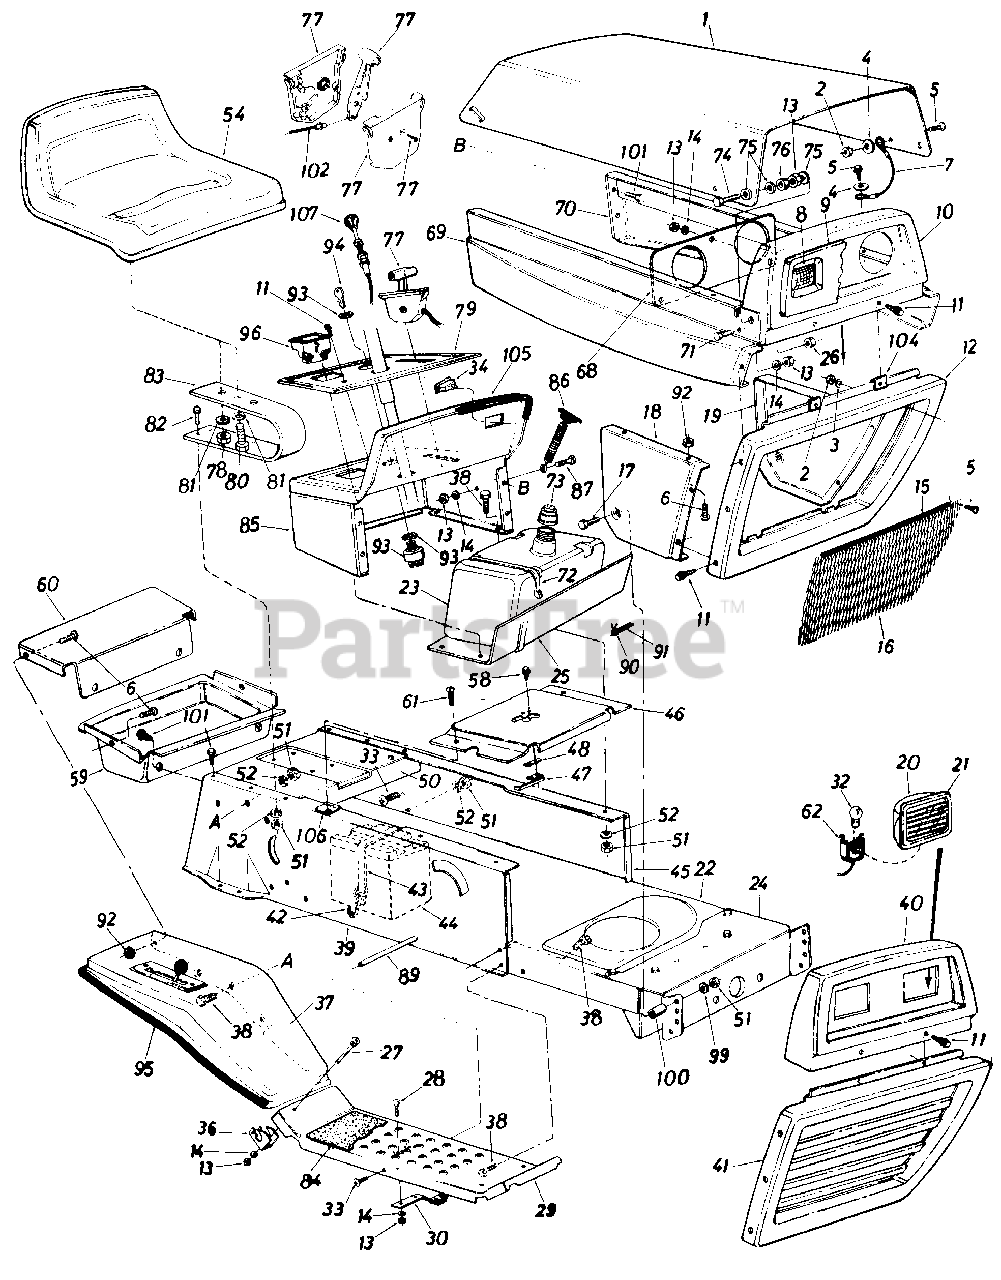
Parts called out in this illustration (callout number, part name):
3	L-Wash. #10 I.D.
4	Fl-Wash. .25" I.D. x .62"
5	Truss Scr. #10-24 x .375"*
6	Truss Hd. Scr. #10-24 x .50"*
7	Hood Stop
8	Headlight
9	Headlight Bezel
10	Front Grille Upper Ass'y.
11	Hex AB-Tap Scr. #10 x .50"
12	Lower Grille
13	Hex Nut 1/4-20 Thd.
14	L-Wash 1/4" I.D.*
15	Vinyl "U"-Channel
16	Grille Screen
17	Hex Bolt 5/16-18 x 1.50"*
18	R.H. Lower Side Panel
19	L.H. Lower Side Panel
20	Headlight Housing
21	Headlight Lens
22	Lower Frame
23	Fuel Tank
24	Front Pivot Brkt.
25	Fuel Tank Support
26	Hex Cent. L-Nut 3/8-16 Thd.
27	Carriage Bolt 1/4-20 x 2.00"*
28	Carriage Bolt 1/4-20 x .62"*
29	Running Board
30	Blade Brake Ass'y.
32	Head Lamp
33	Truss Mach. Scr. 5/16-18 x .75" Lg.*
34	Light Switch
36	Fender Clamp
37	Fender
39	R.H. Side Frame
40	Front Upper Grille Assy.
43	Battery Hold Down Strap
44	12-V Battery
45	L.H. Side Frame
46	Shift Cover
47	Reverse Safety Switch
48	Insulator Nut Plate
50	Hitch Plate
51	Hex Nut 5/16-18 Thd.*
52	L-Wash. 5/16" I.D.*
54	Seat Ass'y.
58	Hex AB-Tap Scr. #8 x .50"
59	Tool Tray
62	Twist Lock-Lamp Socket
68	Head Lamp Retainer
69	Side Panel-R.H.
70	Side Panel-L.H.
71	Hex Bolt 1/4-20 x .62" Lg.*
72	Tie Strap
73	Fuel Cap Gauge
74	Hex Bolt 3/8-16 x 1.00" Lg.*
75	Fl-Wash. 380" I.D. x 1.00"
76	Rubber Wash. .38" I.D. x .87" O.D.
77	Throttle Control Box Ass'y.
78	Hex Nut 1/2-13 Thd.
79	Dash Panel Insert
80	Hex Bolt 1/2-13 x 1.00" Lg.
81	L-Wash. 1/2" I.D.*
82	Hex Bolt 5/16-18 x 1.00"*
83	Seat Spring
84	Foot Pad
87	Hex Bolt 1/4-20 x .50" Lg.*
89	Running Board Rod
90	Hose Clamp
91	Fuel Line
92	Hex Sems Nut #10-24 Thd.
93	Ignition Switch
94	Ignition Key
95	Trim Strip-57" Lg.
96	Ammeter
99	Belleville Wash. .34" I.D.
100	Spacer
101	Hex Wash. Hd. AB-Tap Scr. 5/16 x .75" Lg.
102	Throttle Control Wire
104	Speed Nut #10Z
105	Trim Strip-15"
106	Speed Nut #10Z
107	Choke Control 29" Lg.
